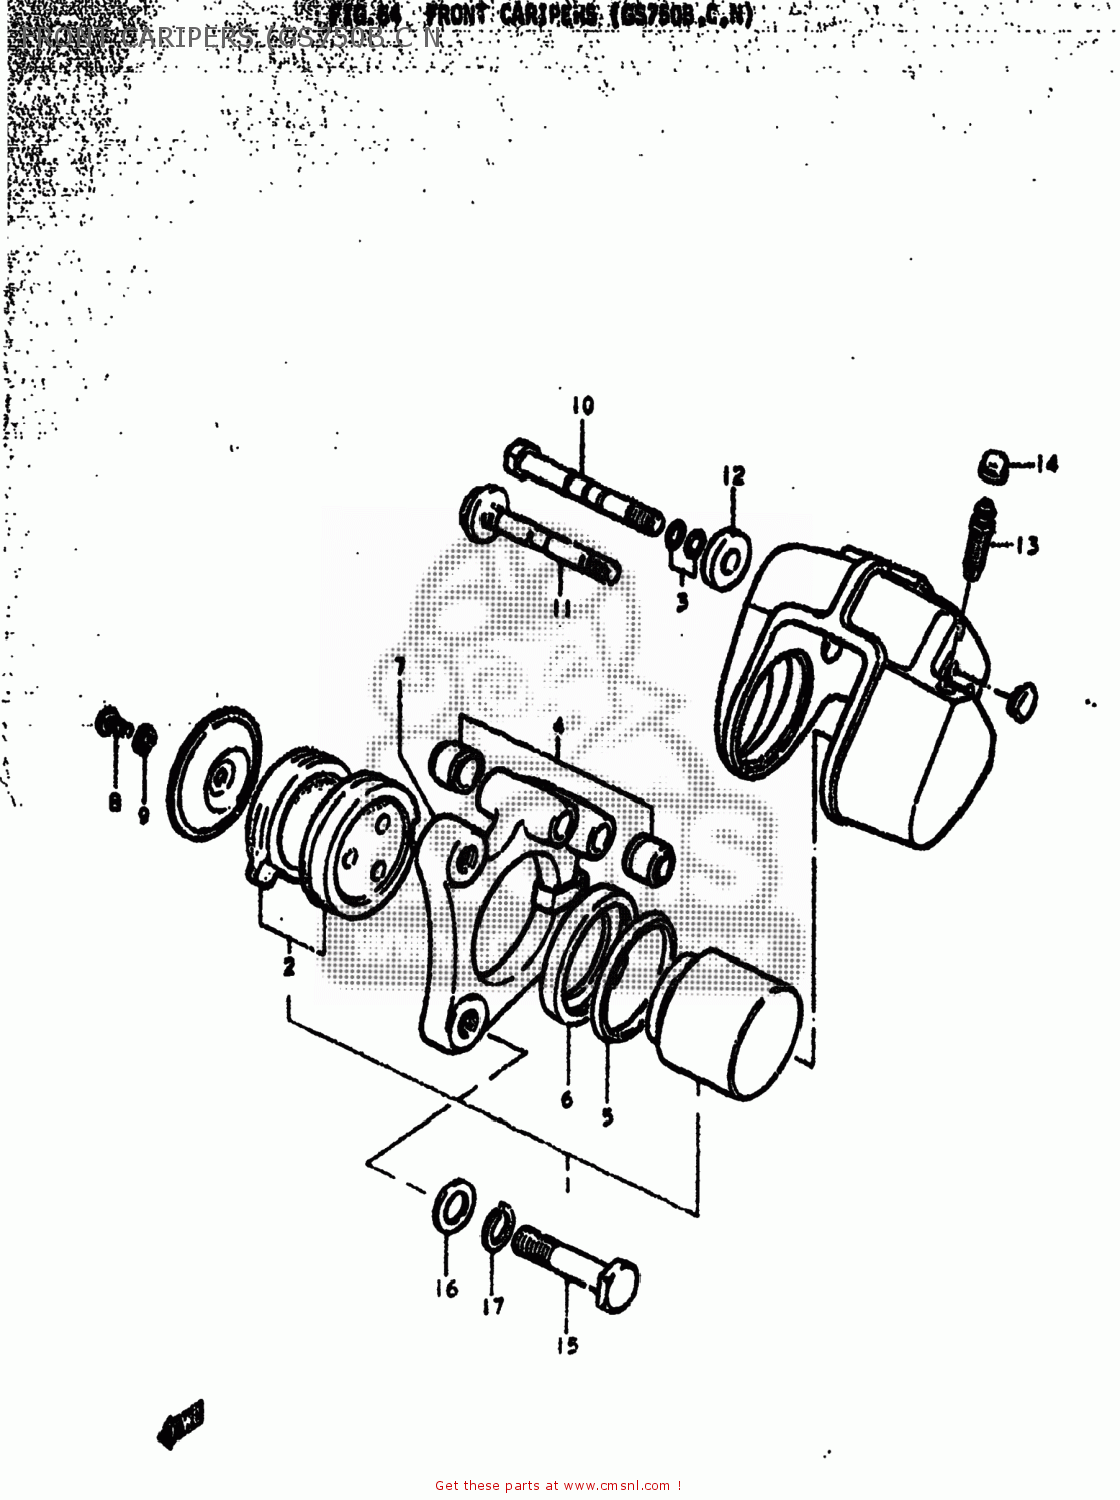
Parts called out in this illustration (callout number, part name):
0	CALIPER ASSEMBLY (ASB)
1	PISTON SET
2	59302-45830 (MCA)
3	O RING
4	COVER,AXLE DUST
5	SEAL,FR CALIPE
6	BOOT,PISTON
7	HOLDER CALIPERS
8	SCREW 6X12
9	LOCK WASHER
10	AXLE,CALIPER
11	AXLE,CALIPER
12	WASHER,AXLE
13	BLEEDER
14	CAP,BREATHER
15	BOLT
16	WASHER
17	LOCK WASHER
